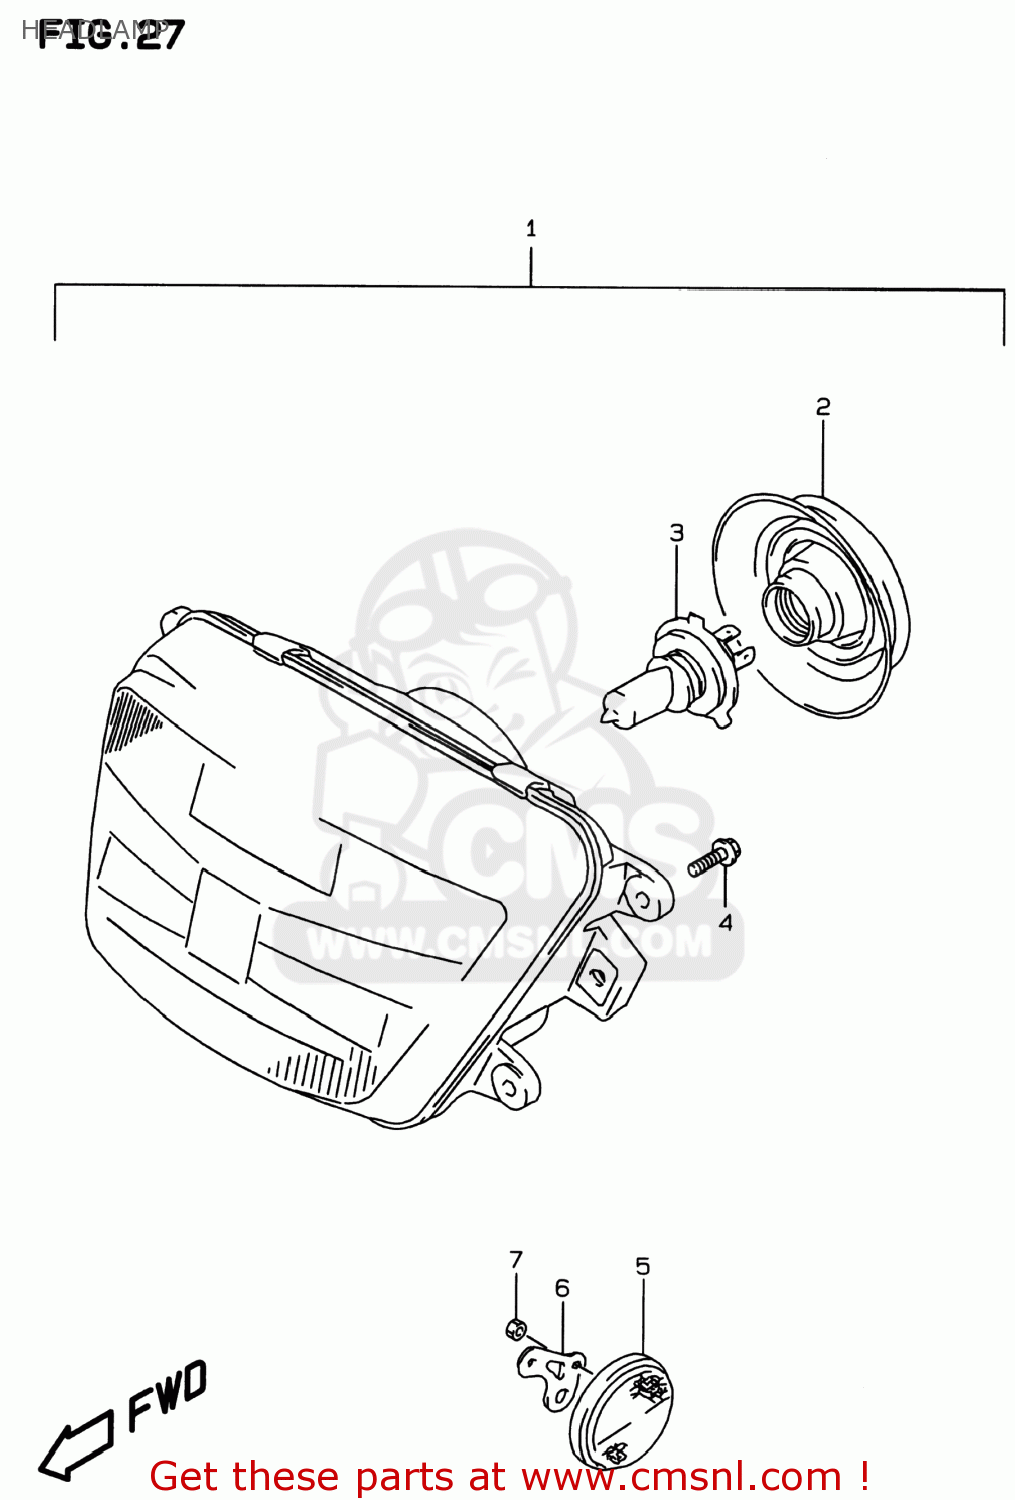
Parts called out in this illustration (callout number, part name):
1	HEADLAMP ASSY
2	COVER,SOCKET
3	BULB(12V60/55W,H4)
4	SCREW
5	REFLECTOR,REFLEX FR
6	BRACKET,FR SIDE REFLECTOR
7	NUT
